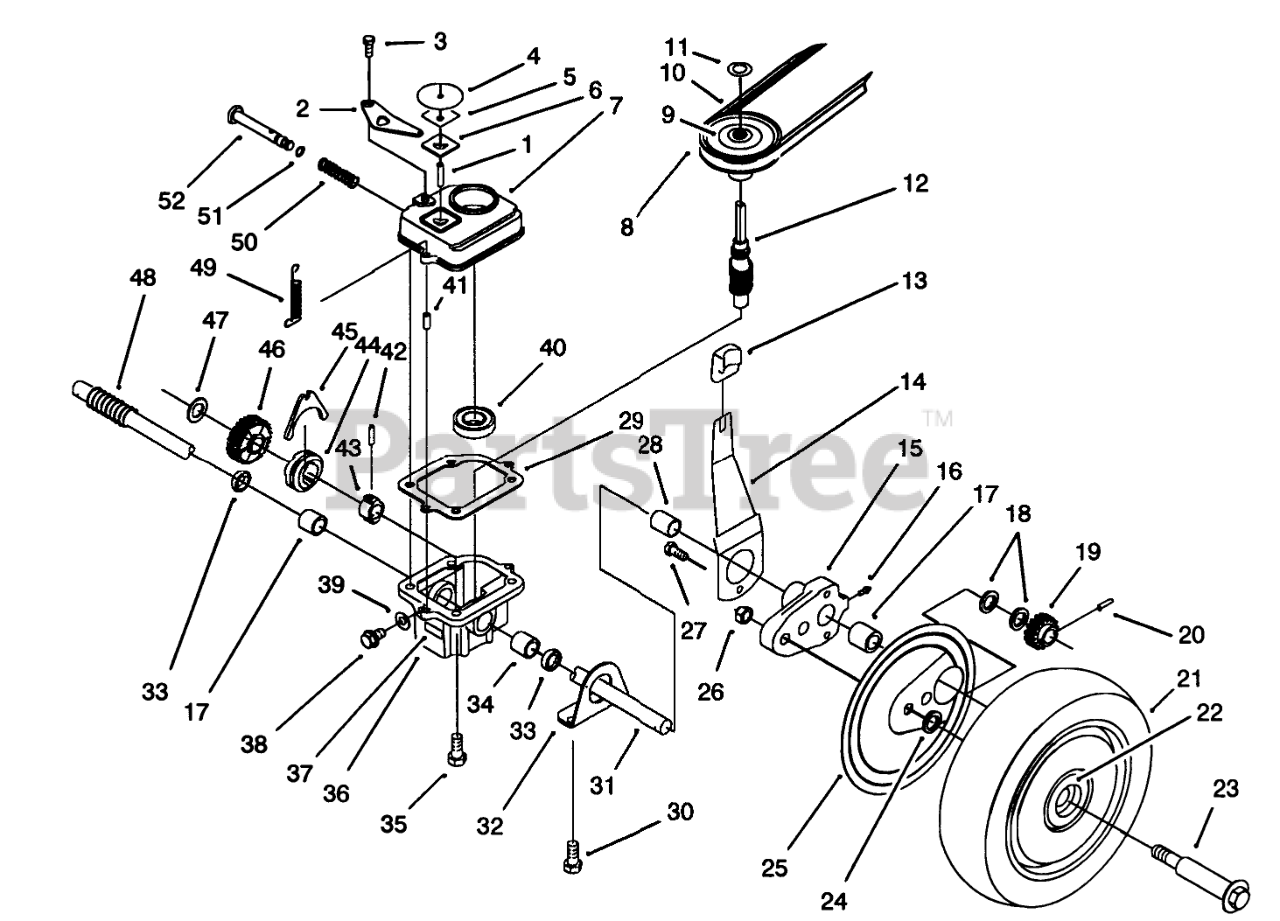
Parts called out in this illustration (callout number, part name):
1	SPIROL PIN H D
2	SHIFTER ARM
3	Screw
4	DUST COVER
5	DUST FILTER
6	LATCH PLATE
7	GEAR CASE COVER
8	PULLEY
9	DECAL
10	V BELT
11	PUSH-ON 93-3236
12	Worm Shaft & Gear (Incl. Ref. #46)
13	KNOB-ARM
14	SPRING ARM ASSY-FRONT
15	Arm-Pivot (Incl. Ref. #16, 17 & 28)
16	FITTING-GREASE
17	BUSHING
18	THRUST WASHER
19	PINION GEAR 15T
20	Pin
21	Wheel, Tire & Gear Assy (Incl. Ref. #22)
22	BUSHING
23	WHEEL BOLT
24	WASHER
25	WHEEL COVER
26	NUT-LOCK
27	SCREW
28	BUSHING
29	GASKET
30	SCREW-HWHTF
31	DRIVE SHAFT
32	END CAP
33	SEAL-OIL
34	BUSHING
35	Screw
36	Gear Case (Incl. Ref. #17, 23 & 34)
37	DECAL
38	NYLON SCREW
39	FILL PLUG GASKET
40	BEARING
41	3/16 X 1/2 ROLL PIN
42	COIL PIN
43	SLEEVE
44	CLUTCH JAW
45	SHIFTER FORK
46	Gear-Helical
47	THRUST WASHER
48	COVER-SHAFT, DRIVE
49	TENSION SPRING
50	SPRING
51	O-RING
52	SHIFTER ROD
